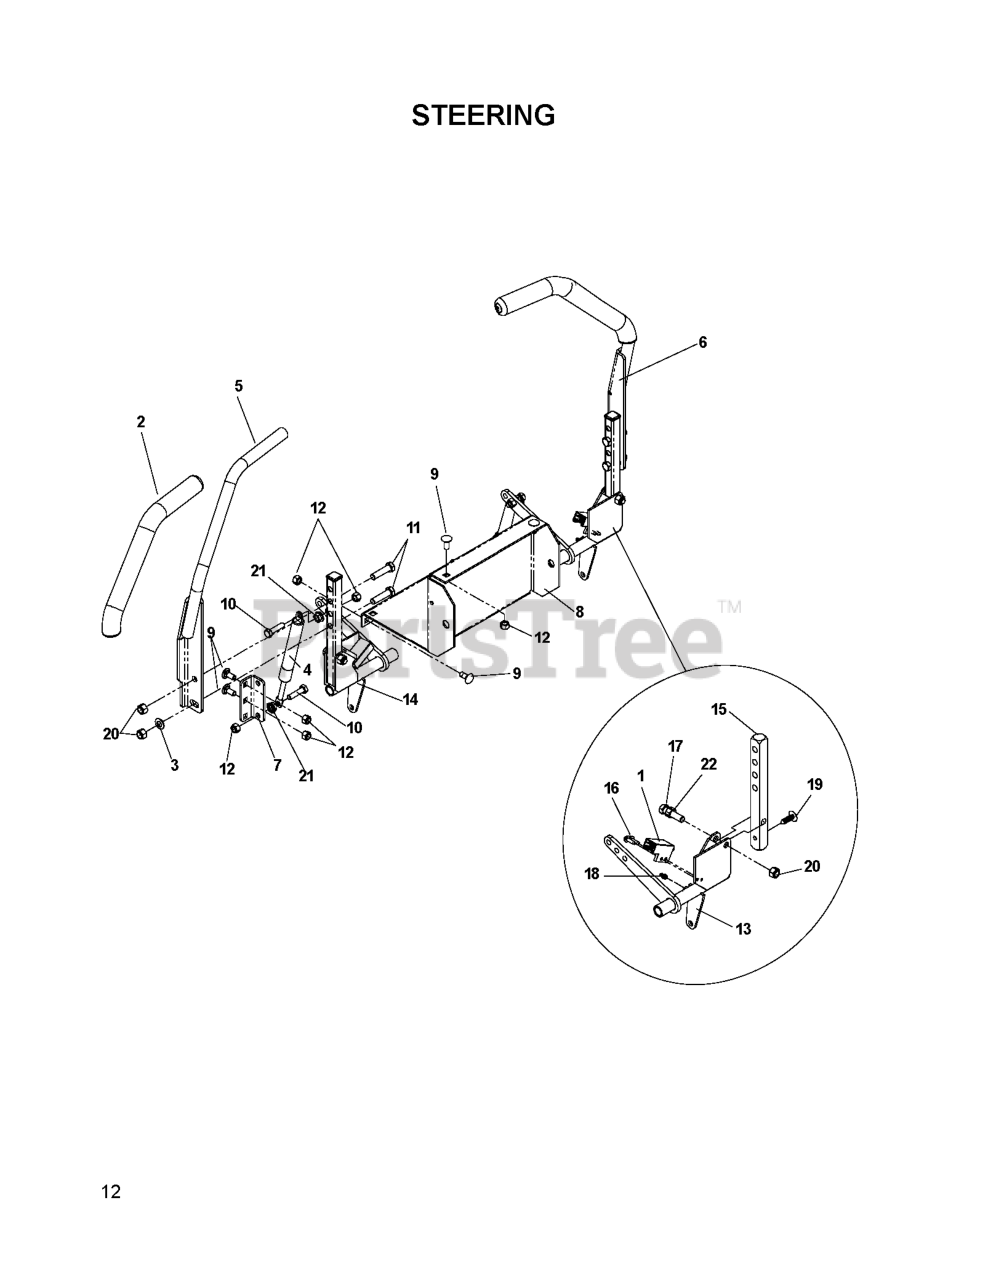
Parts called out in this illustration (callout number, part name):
1	SWITCH, INTERLOCK
3	WASHER, 3/8 DISC SPRING SPEC
5	RT DRIVE LEVER WLDMT
6	LT DRIVE LEVER WLDMT
7	DAMPENER BRACKET
8	BATTERY TRAY
9	BOLT 5/16C X 3/4" CARRIAGE
10	HCS 5/16C X 1 1/4
11	HCS 3/8C X 1 1/2
12	NUT 5/16 NYLOC
13	CONTROL WELDMENT, LEFT
14	CONTROL WELDMENT, RIGHT
15	CONTROL ARM
16	SCREW #10 X 1/2 SELF TAPPING
17	HCS 3/8-16 X 2-1/2 TPBLT
18	ZERK
19	RIVET, NYLON PUSH-IN
20	NUT 3/8-16 NYLOC
21	NUT 5/16C WHIZ
22	NUT 3/8C CENTERBLOCK
